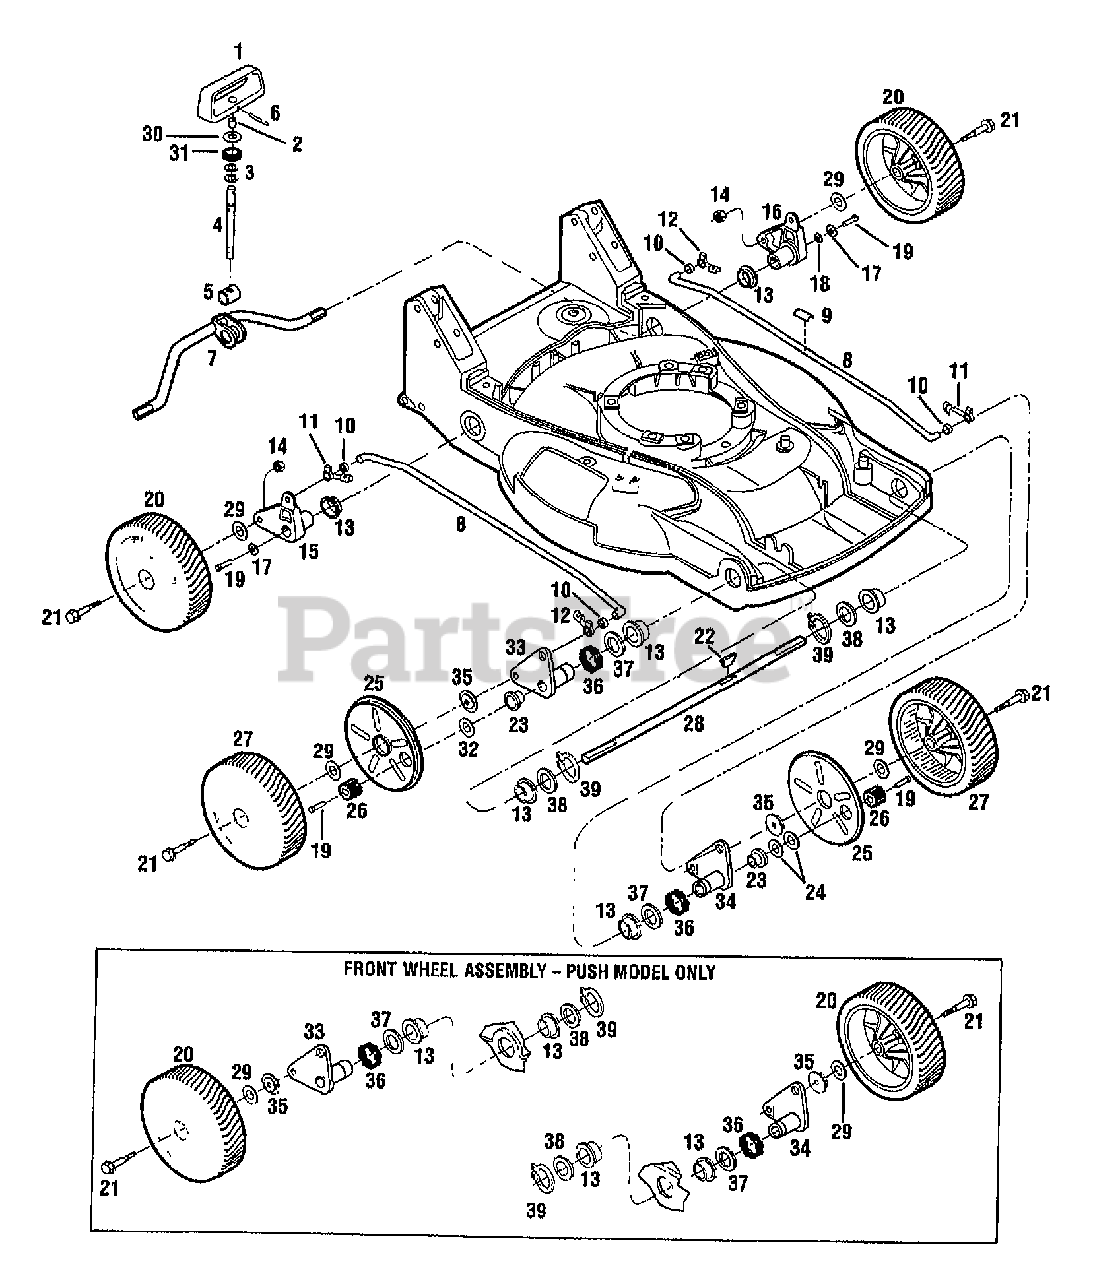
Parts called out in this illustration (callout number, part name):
1	HANDLE-HEIGHT ADJ
2	SPACER-HANDLE
3	WASHER-#.88X.51X.063
4	SCR-HANDLE ADJUST
5	PIVOT-SCR ADJUST
6	PIN-ROLL .188X1.0
7	AXLE-REAR E-COATED
8	LINK-HEIGHT ADJ PNT
9	DECAL-INDICATOR
10	BEARING-NYLINER
11	CLIP-ROD (RIGHT REAR / LEFT FRONT)
12	CLIP-ROD (LEFT REAR / RIGHT FRONT)
13	BEARING-AXLE ARM REAR
14	NUT-H/LK 3/8-16
15	ARM-AXLE W/BUSHING RH
16	ARM-AXLE W/BUSHING LH
17	WASHER-.78X.25X.08
18	WASHER-.5X.25X.06
19	SCR-HXSKT 1/4-20X.75 NYL
20	ASSM-TIRE & WHEEL
21	SCR-SHLDR MOD. RADIUS
22	KEY-WOODRUFF .125X.5 {NOT 34320 34320C,34044}
23	BEARING-CARRIER {NOT 34320 34320C34044}
24	WASHER-.92X.5X.03 HT {NOT 34320 34320C,34044}
24	WASHER-.92X.5X.016 HT {NOT 34320 34320C, 34044}
25	SHIELD-WHEEL W/STEP {NOT 34320 34320C,34044}
26	PINION-DRIVE {NOT 34320 34320C,34044}
27	ASSM-TIRE & WHEEL (DRIVE) {NOT 34320 34320C, 34044}
28	AXLE-DRIVE ROUND NGMM {NOT 34320 34320C, 34044}
29	WASHER-.88X.406X.09
30	WASHER-SPEC
31	WASHER-RUBBER
32	WASHER-THRUST .92X.5X.06 {NOT 34320 34320C, 34044}
33	ARM-WHEEL RT
34	ARM-WHEEL LT
35	HUB-WHEEL SPACER
36	SPRING-CREST
37	WASHER-THRUST
38	WASHER-SPEC
39	RING-HEAVY EXT .984 ID
